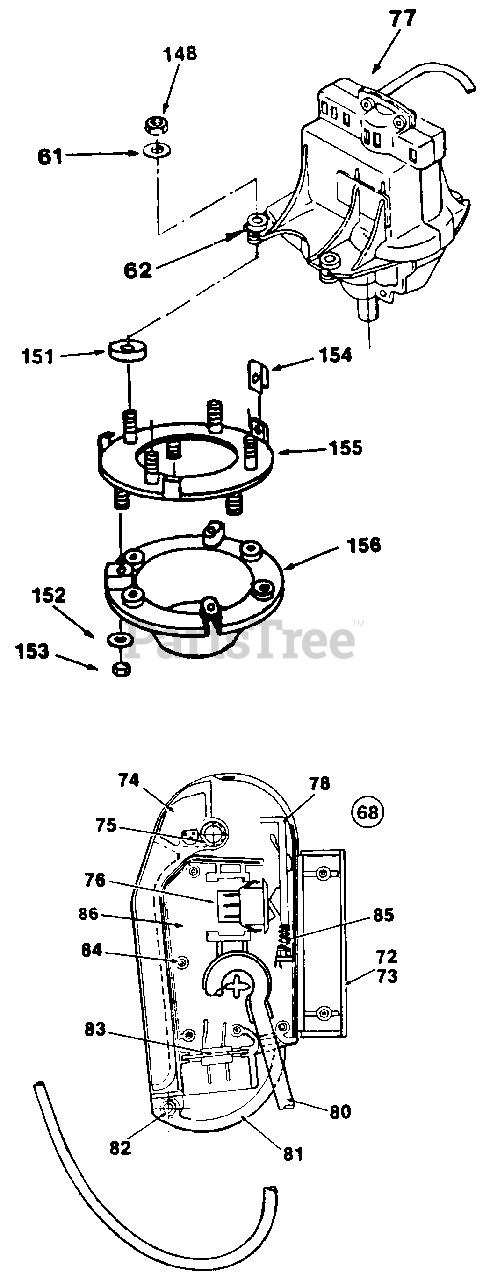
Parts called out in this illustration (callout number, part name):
61	Fl-Wash. .26" I.D. x .72" O.D.
62	Motor Housing Insulator
68	Cord & Switch Box (Complete)
72	Housing-Upper Half
74	Handle-Switch Actuator
75	Spring-Switch Handle
76	Switch
77	Motor & Switch Ass'y.
78	Latch
80	Cord Ass'y.
81	Retainer Plug
82	Retainer Plug Spring
83	Plug Ass'y.
84	Screw #6-32 x .5" Lg.
85	Latch Spring
148	Nylon Top L-Nut 1/4-20 Thd.
151	Spacer
152	Fl-Wash. 5/16" I.D. x .75" O.D.
153	Nylon Top L-Nut 5/16-18 Thd.
155	Motor Mount Plate Ass'y.
156	Motor Shield
